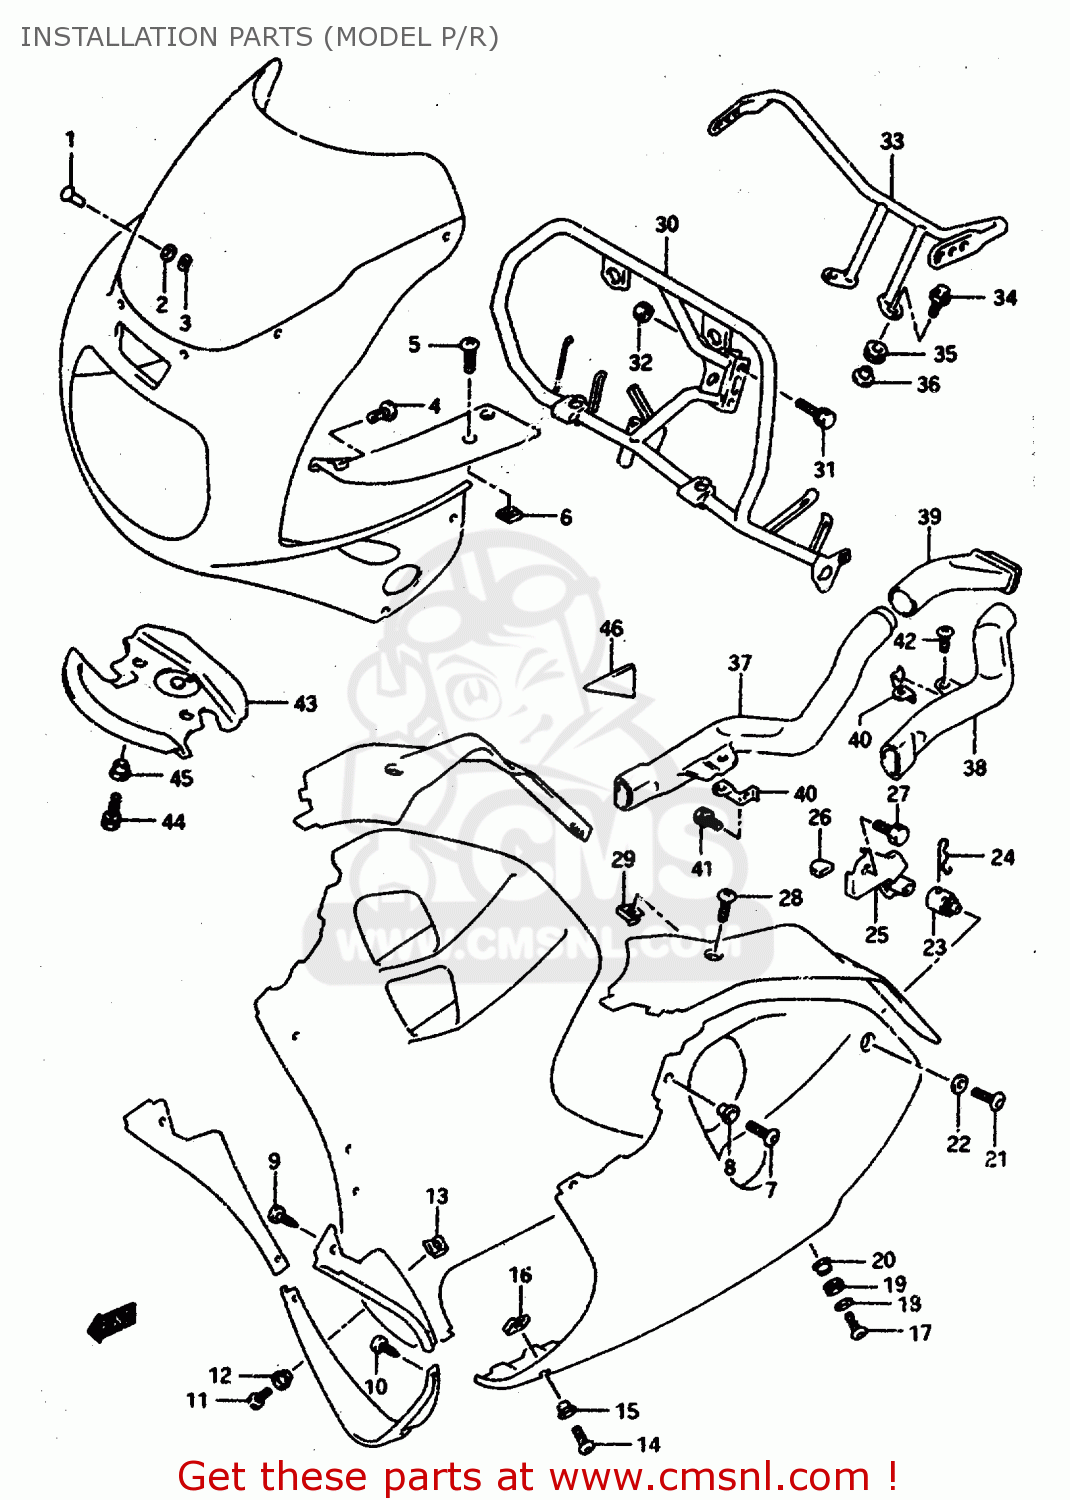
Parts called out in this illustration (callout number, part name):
1	PIN,WINDSCREEN
2	CUSHION
3	NUT
4	SCREW 5X12
5	SCREW
6	NUT
7	SCREW(5X18)
8	WASHER(5.2X14X1.5)
9	SCREW 5X10
10	SCREW 5X10
11	SCREW(5X18)
12	WASHER(5.2X14X1.5)
13	NUT,HEADLAMP HOUSING,UPPER
14	SCREW(5X18)
15	WASHER(5.2X14X1.5)
16	NUT,HEADLAMP HOUSING,UPPER
17	SCREW(6X25)
18	WASHER(6.5X18X1)
19	CUSHION
20	WASHER
21	SCREW(6X20)
22	WASHER
23	PLUG,UNDER COWL FTG,CTR
24	PIN,UNDER COWLING FITTING PIPE
25	BRACE,UNDER COWLING UPR,R
26	CUSHION,UPR BRACE
27	BOLT
28	SCREW
29	NUT
30	BRACE,COWLING
31	BOLT
32	NUT
33	BRACE,RR VIEW MIRRORR
34	BOLT 6X20
35	CUSHION
36	WASHER
37	PIPE,AIR INTAKE,FRONT
38	PIPE,AIR INTAKE,FRONT
39	PIPE, AIR INTAKE REAR RH
40	BRACKET,AIR INTAKE,LEFT
41	BOLT
42	SCREW 6X12
43	COVER,COWLING FR LWR
44	BOLT
45	WASHER
46	CUSHION,AIR INTAKE PROTECTOR,R
